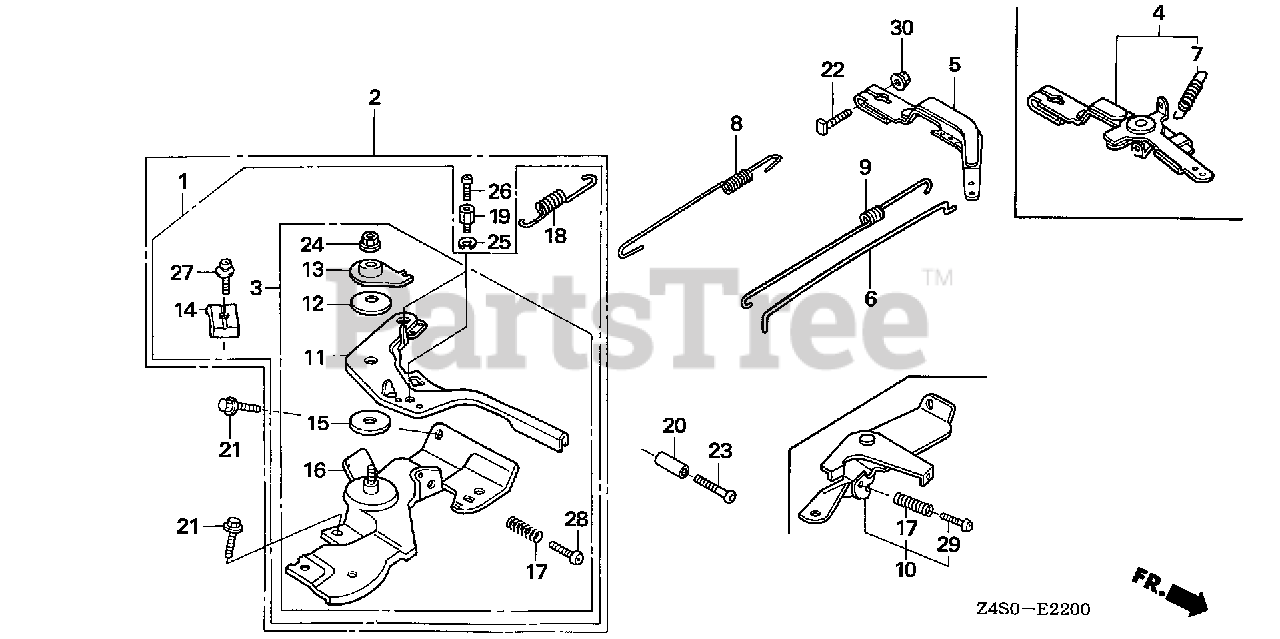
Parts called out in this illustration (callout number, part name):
1	CONTROL ASSY. (REMOTE)
5	ARM, GOVERNOR
6	ROD, GOVERNOR
8	SPRING, GOVERNOR
9	SPRING, THROTTLE RETURN
11	LEVER, CONTROL
12	SPRING, LEVER
13	WASHER, CONTROL LEVER
14	HOLDER, CABLE
15	SPACER, CONTROL LEVER
16	BASE, CONTROL (REMOTE)
17	SPRING, CONTROL ADJUSTING Use from Engine SN 2327377.
18	SPRING, CABLE RETURN
21	BOLT, FLANGE (6X12) (CT200)
22	BOLT, GOVERNOR ARM
24	NUT, SELF-LOCK (6MM)
27	SCREW, PAN (5X16)
28	SCREW, PAN (5X25)
30	NUT, FLANGE (6MM)
